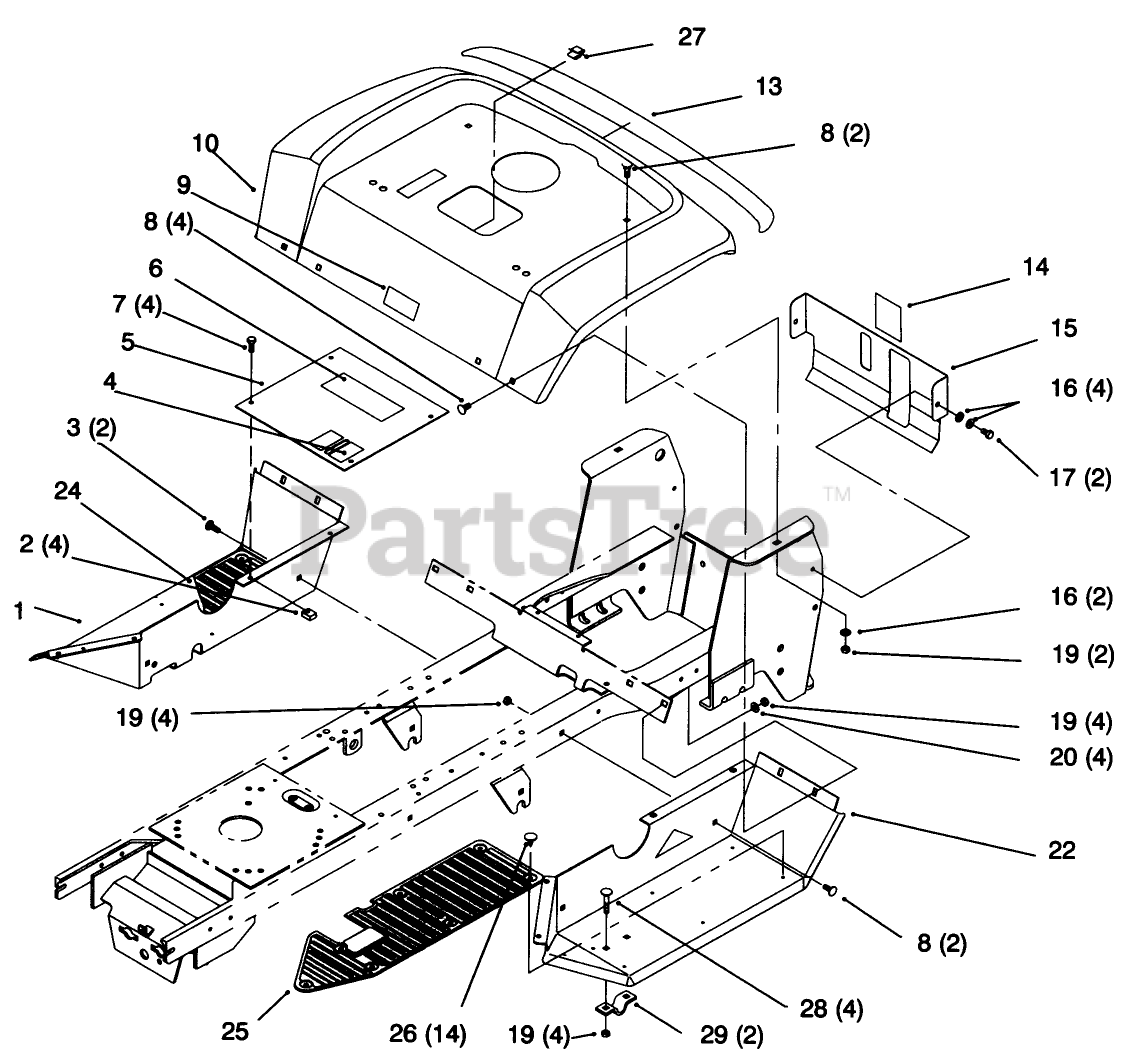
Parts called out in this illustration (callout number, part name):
1	FOOTREST-RH
3	SCREW-CARR
4	DECAL - HOC
5	PLATE/DECAL ASM-FOOTREST
6	DECAL-DANGER
7	SCREW-HH
8	BOLT-CARR
9	DECAL - USA
13	DECAL - REAR FENDER
14	DECAL-LEVEL, FUEL
15	COVER-REAR
16	WASHER-PLAIN
17	SCREW
19	NUT-LOCK, NI
20	WASHER-FLAT
22	LH FOOTREST
22	FOOTREST-LH
24	FOOTPAD-RH
24	FOOT MAT-RH
25	FOOTPAD-LH
25	FOOT MAT-LH
26	FASTENER-PANEL
27	CLIP-RETAINER, WIRE
29	CLAMP
